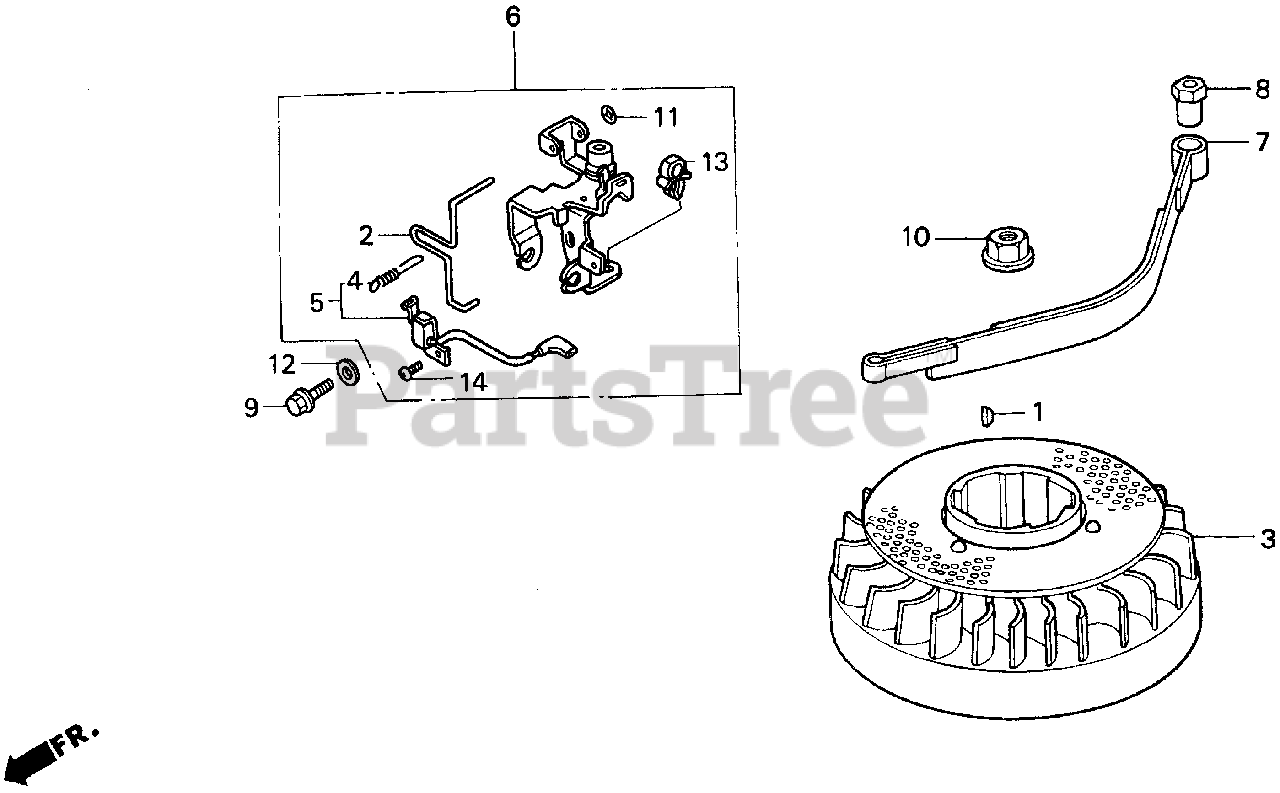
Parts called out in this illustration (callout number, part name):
1	KEY, SPECIAL WOODRUFF (25X18)
2	ROD, GOVERNOR ARM RETURN
3	FLYWHEEL ASSY.
4	SPRING, SWITCH CONTROL
5	SWITCH ASSY., ENGINE STOP (BRAKE)
6	LEVER ASSY., BRAKE
7	BRAKE
8	COLLAR, BRAKE SHAFT
9	BOLT, FLANGE (6X14)
10	NUT, SPECIAL (14MM)
11	NUT, SPEED
12	WASHER, SEALING (6.2X12X1.2)
13	CLIP, ENGINE STOP SWITCH CORD
14	SCREW, PAN (4X6)
